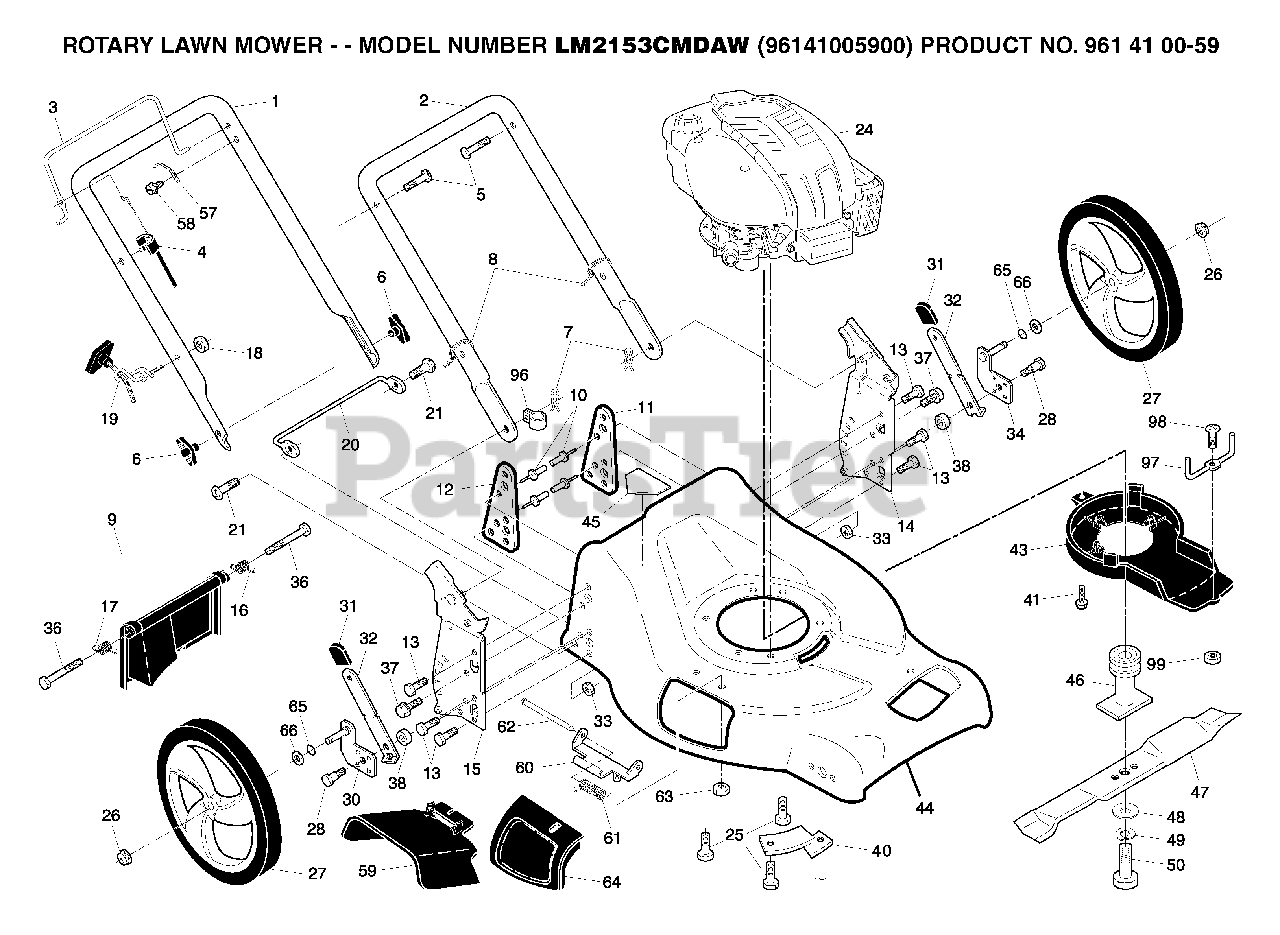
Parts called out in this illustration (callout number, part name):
1	HANDLE.UPER.D.ST.EZ
2	LOWER HANDLE
4	CABLE.MZR
5	BOLT, HANDLE 5/16-18X1.75
6	HNDL.KNOB.GRAY
7	HAIRPIN COTTER
8	TIE GUIDE
9	REAR DOOR KIT.
10	RIVET BLIND
11	SUPPORT BRACKET LH
12	SUPPORT BRACKET RH
13	SCREW 14-20 X 5/8
14	BRKT.ASM.HNDL.21FGD
15	BRKT.ASM.HNDL.21FGD.EZ
16	SPRING LH
17	SPRING.REAR.DOOR.EZ.21
18	NUT
19	GUIDE.ROPE.STD.BLK.ZIN
25	BOLT 3/8-16X1-1/8
26	NUT
28	SHOULDER BOLT
30	ARM.ASM.AXLE.H/W,RR.BZ
31	SELECTOR KNOB
32	SPRING.SELECTOR.21.FWG
33	NUT.71038.31-18.HEX.NYLOCK
34	ARM.ASM.AXLE.H/W.LR.BZ
37	SELF-TAPPING SCREW 5/16-18X3/4
38	WASHER.FLAT.34X1.38X22
40	BRACKET
41	SCREW.HEX.WSH
43	DEBRIS SHIELD
45	DECAL.INTERNATIONL.CUTFINGER
47	BLADE.21.PUSH
48	WASHER,HARDEN
49	LOCKWASHER
50	SCREW, HEX HD 3/8-24 X 1-3/8
57	BRACKET UPSTOP
59	DISCHARGE DEFLECTOR
60	HINGE BRACKET ASSEMBLY
61	SPRING.TORSION
62	ROD.HINGE.21
63	LOCKNUT
64	DOOR.MULCH.21.REAR
65	O-RING..070X.487.NEOPRENE
66	WASHER PM
96	CLIP.CABLE.BLK
97	KEEPER.BELT.FGD
99	NUT.HEX.#8
